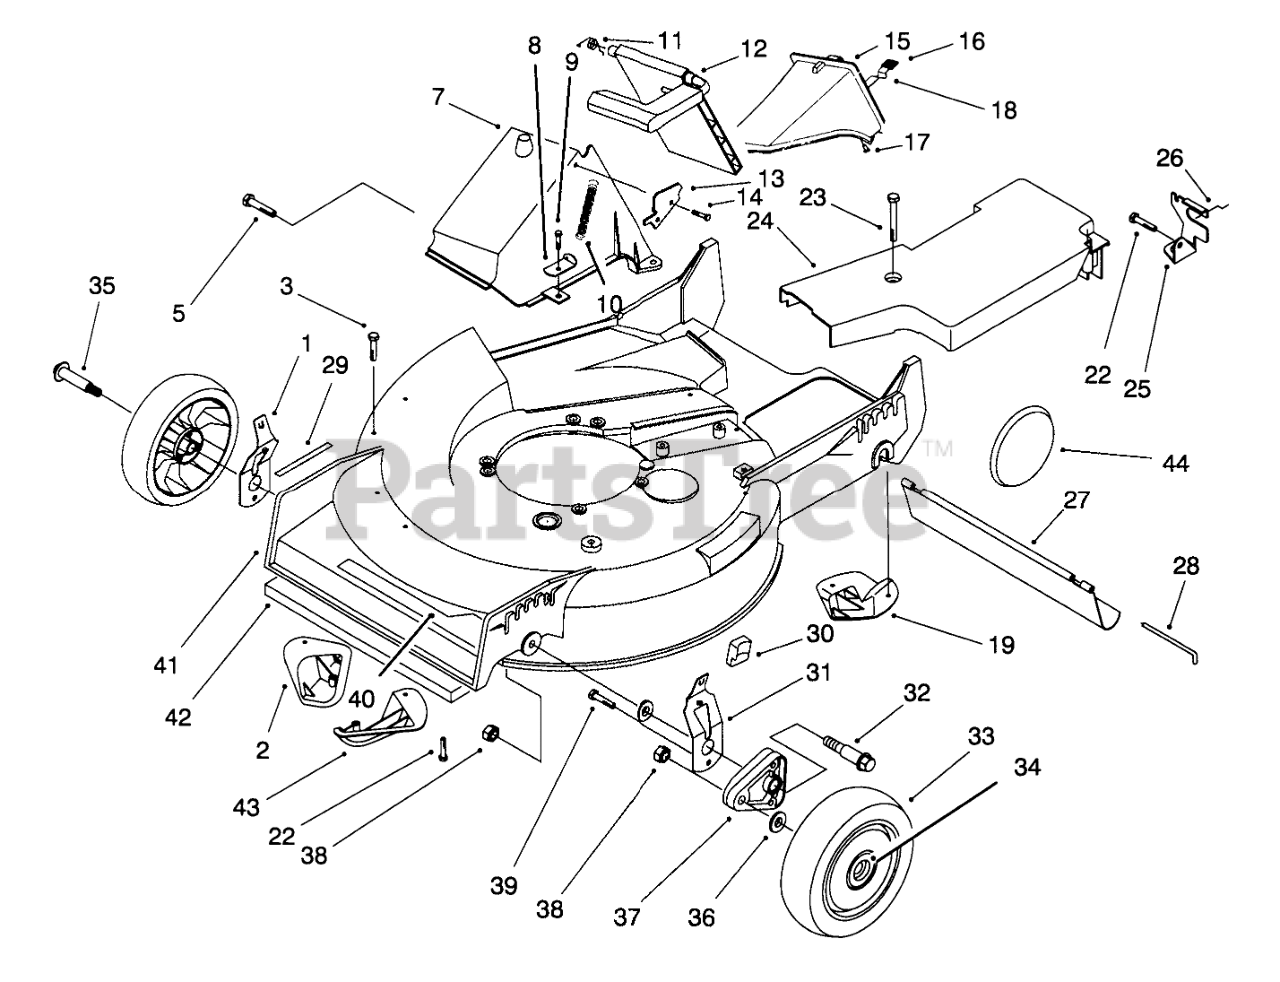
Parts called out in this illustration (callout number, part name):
1	RH SPRING ARM ASSEMBLY
2	KICKER-RH
3	SCREW-PPH
5	SCREW AND WASHER ASM
7	TUNNEL-DISCHARGE
8	BRACKET-SPRING
9	SCREW-HWH
10	SPRING-DOOR
11	RETAINER-DOOR
12	DOOR ASSEMBLY
13	DOOR LATCH PLATE
14	SCREW-PLASTITE
15	Plug Assembly(Incl. Ref. #16-18)
16	GRIP-LATCH
17	RIVET-HEAD, FLAT
18	LATCH-PLUG, DISCHARGE
19	KICKER-REAR
22	SCREW-HWHTF
23	SCREW-HHFTF
24	BELT COVER
25	Bracket-Adj. Trac
26	RETAINER-CABLE
27	SHIELD-TRAILING
28	ROD-SHIELD
29	DECAL - HOC
30	KNOB-ARM
31	LH SPRING ARM ASSEMBLY
32	BOLT-SHOULDER
33	Wheel & Tire Assembly(Incl. Ref. #34)
34	BUSHING
35	BOLT-WHEEL
36	WASHER
37	ARM-PIVOT, FRONT
38	NUT-LOCK
39	SCREW-HWH
40	DECAL - DECK
41	Housing Assembly (Incl. Ref. #2,3,19,29,43 pg. 2)(Incl. Ref. #5 & 6 pg. 3)
42	Shield-front
43	KICKER-FRONT
44	COVER-WHEEL
